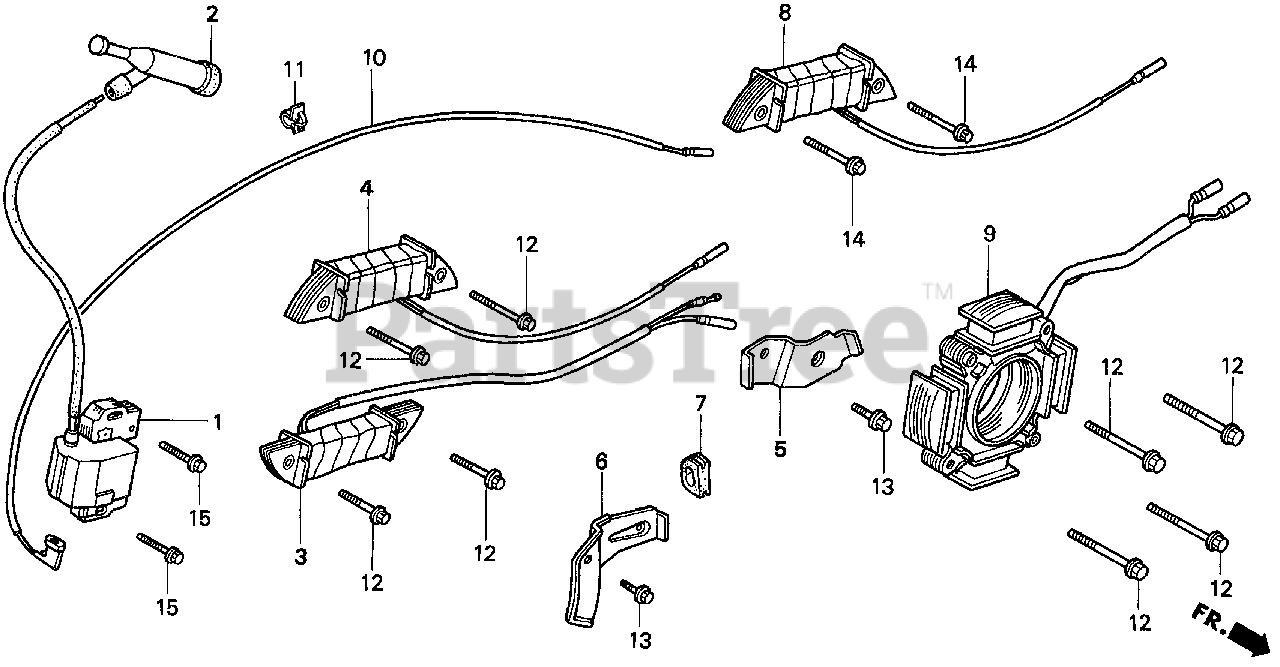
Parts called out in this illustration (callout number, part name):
1	COIL ASSY., IGNITION
2	CAP ASSY., NOISE SUPPRESSOR
3	COIL ASSY., LAMP (12V/25W)
6	CLAMP, WIRE
7	GROMMET, WIRE
10	WIRE, STOP SWITCH (470MM)
12	BOLT, FLANGE (6X40)
13	BOLT, FLANGE (6X12) (CT200)
15	BOLT, FLANGE (6X28)
